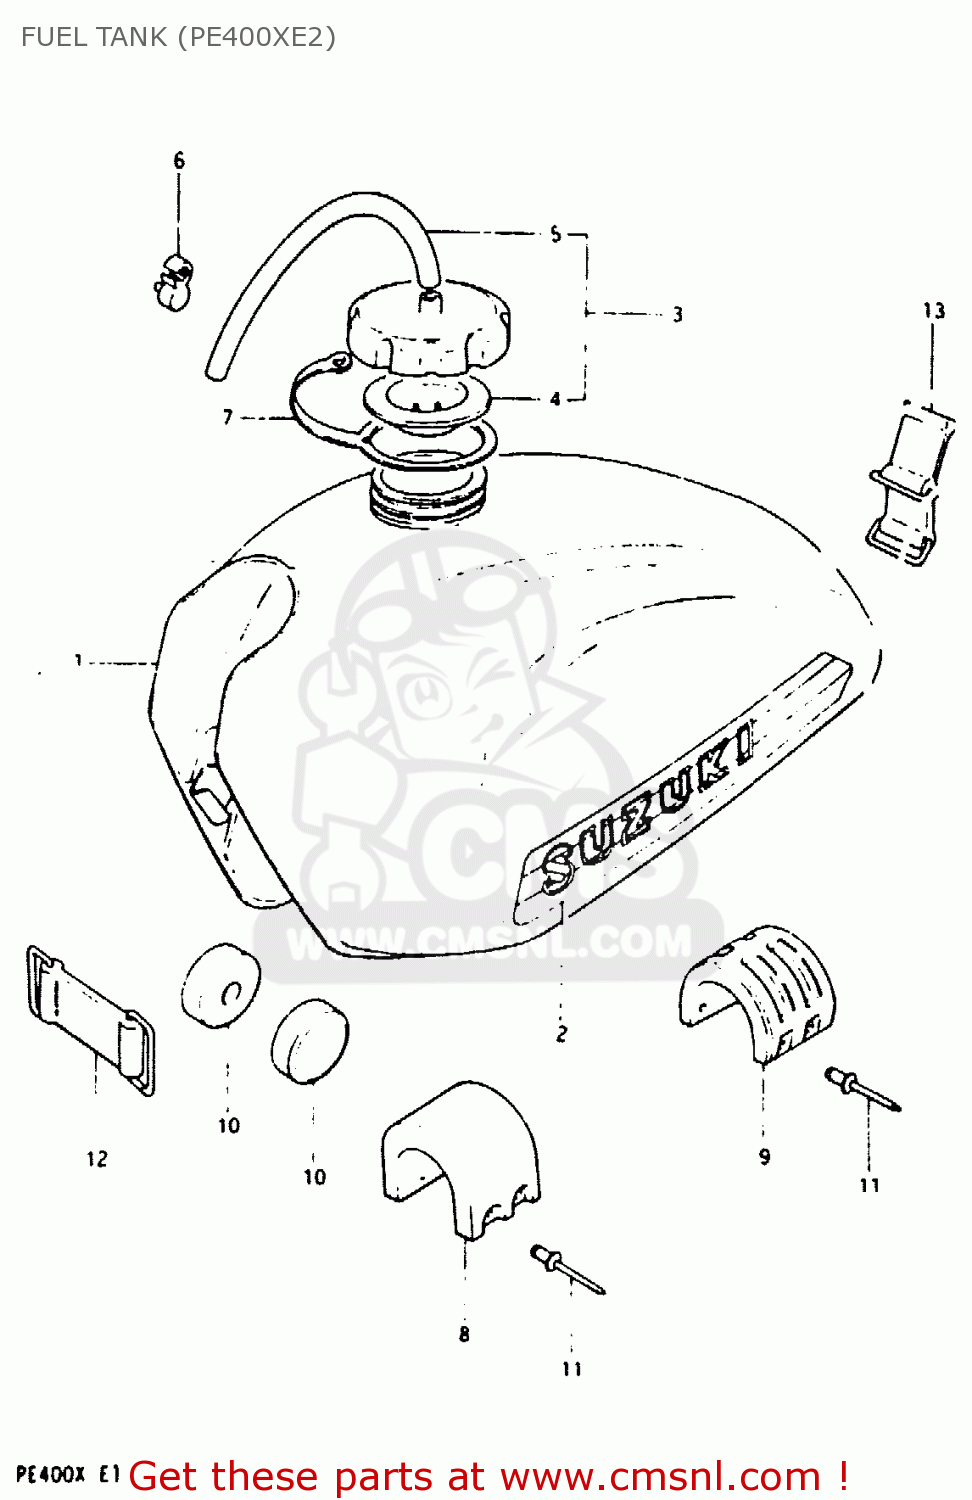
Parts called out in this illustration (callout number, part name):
1	TANK, FUEL (YELLOW)
2	TAPE SET,FUEL TANK
3	CAP ASSEMBLY,FUEL TANK
4	GASKET,FUEL TANK CAP (NAS)
5	HOSE
6	CLAMP,BREATHER HOSE
7	BAND,FUEL TANK CAP
8	CUSHION, UPPER FRONT
9	CUSHION,FUEL TANK,CENTER
10	CUSHION
11	RIVET
12	BAND
13	BNAD, REAR
